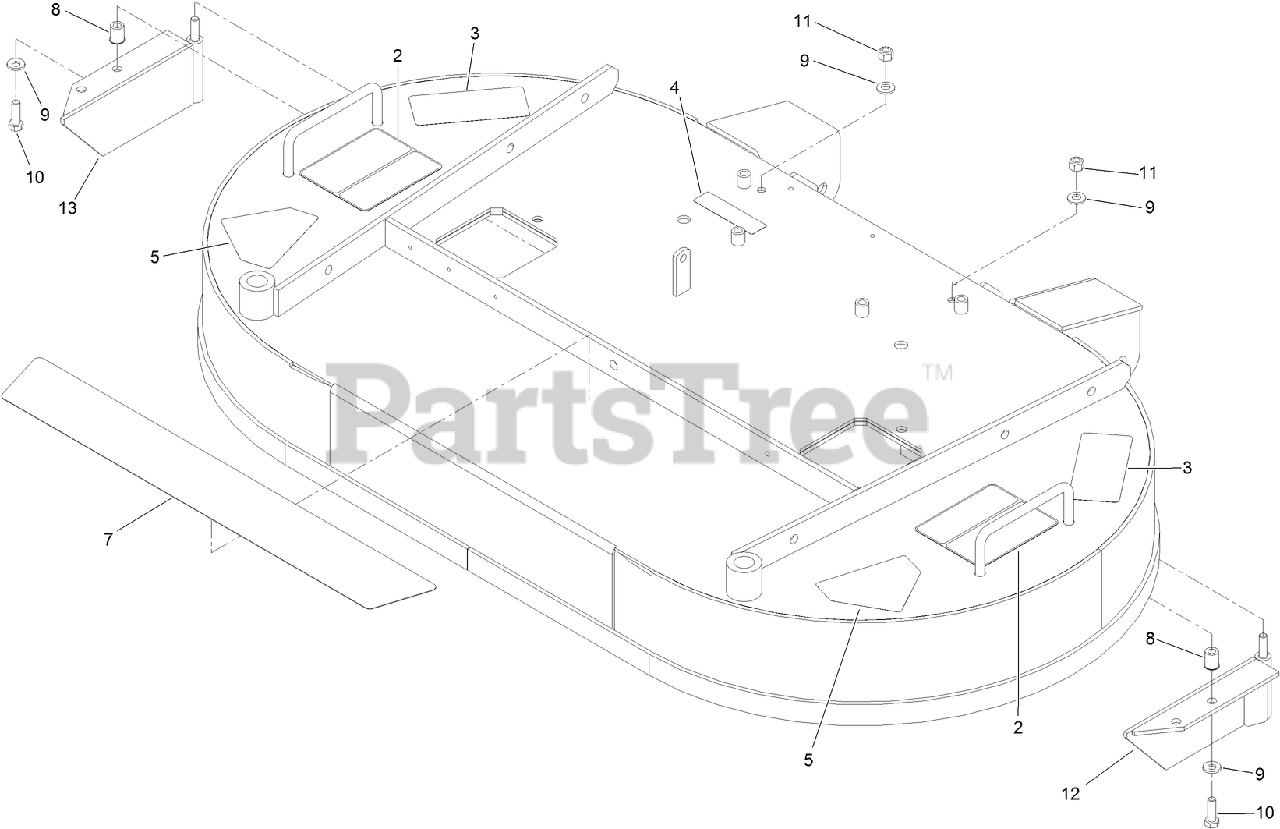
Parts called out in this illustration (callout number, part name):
2	DECAL-CUTTING HEIGHT ADJUSTMENT
3	DECAL-TORQUE
4	DECAL-COVER, MISSING
5	DECAL-DANGER
7	PAD-ANTI SKID
8	NUT-INSERT
9	WASHER-SPRING
10	SCREW-HH
11	NUT-LOCK, NI
12	BAFFLE-LH
13	BAFFLE-RH
